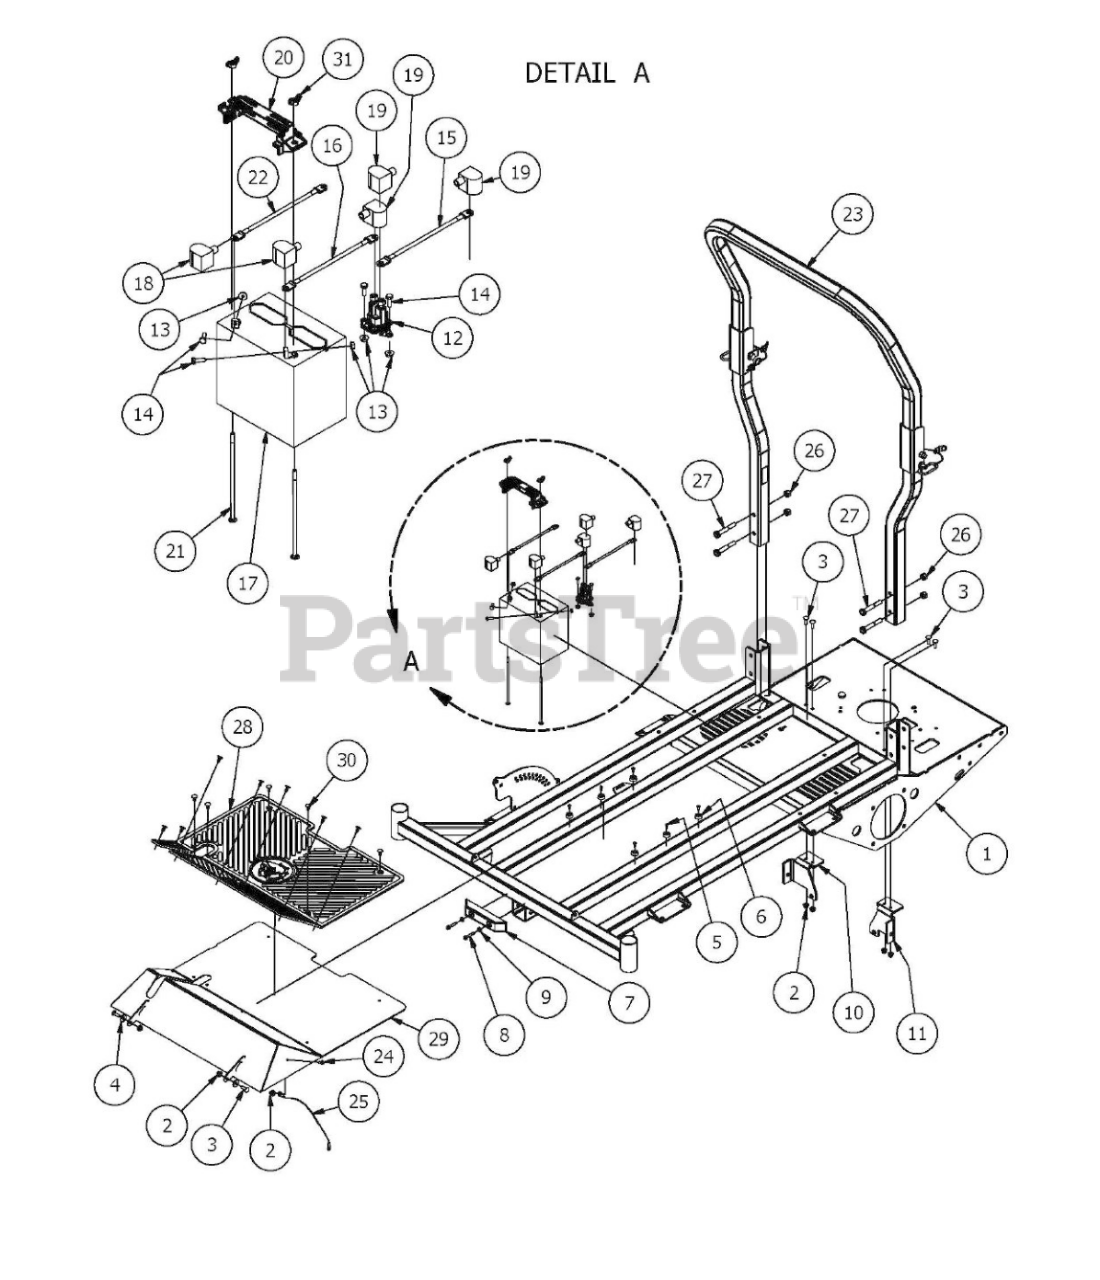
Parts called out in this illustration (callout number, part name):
1	2017 Standard/Extreme Outlaw Frame
2	5/16" Nylock Flange Nut Zinc
3	5/16" x 1" Carriage Bolt
4	.360 ID Plastic Washer
5	#10 x 1/2" Self Tapping Screw
6	Button Bumper
7	8" Rubber Bumper
8	1/4" x 1 1/2" Self Tapping Screw
9	1/4" Flat Washer
10	Outlaw Brake Cable Mount Bracket (Right)
11	Outlaw Brake Cable Mounting Bracket (left)
13	1/4-20 Hex Flange Nuts Zinc w/Serrations
14	1/4-20 x 3/4 GR 5 Hex Bolts Zinc
15	Red Battery Cable Alternator to Starter Cable
16	12 in red battery cable
18	Black Boot For Ground Cable
20	Battery Hold Down
21	1/4-20 X 8 Carriage Bolt
22	Ground Cable
23	2015 Outlaw 2x2 Folding ROPS
24	1/4" x 5/8" BS C/S 18-8 SS
25	Floor board Cable W/ Swivel Ends
26	1/2" Center Lock Nut
27	1/2-13 X 3.25 Hex Bolt - Grade 5
28	2016 Outlaw Floor Mat
29	2016 Outlaw Floor Panel
30	Ratchet Fastener
31	1/4" Wing Nut
